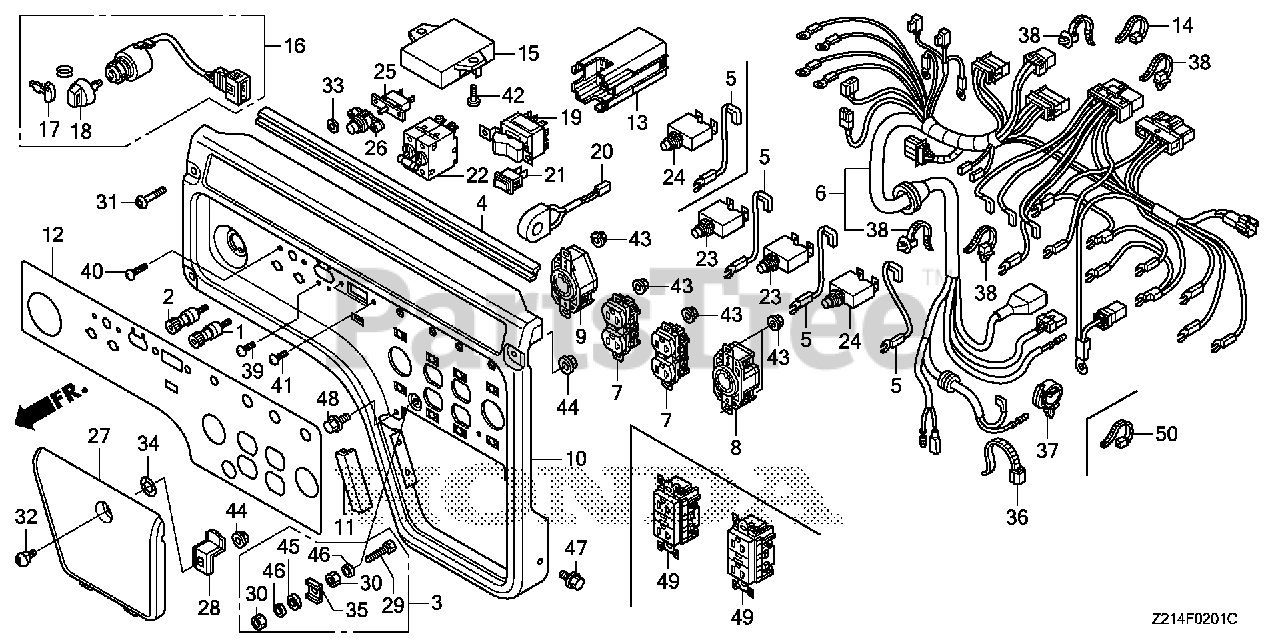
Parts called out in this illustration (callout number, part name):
1	TERMINAL, D.C. OUT (+)
2	TERMINAL, D.C. OUTPUT (-)
3	TERMINAL SET, GROUND
4	RUBBER, CONTROL PANEL
5	SUB-WIRE ASSY. (A)
6	WIRE HARNESS ASSY., CONTROL
8	RECEPTACLE (20A-125/250V)
9	RECEPTACLE (30A-125V)
10	PANEL, CONTROL (EM-A1) *R280* (POWER RED)
11	RUBBER, CONTROL PANEL (LOWER)
12	MARK, PANEL (EM-A1)
13	CONNECTOR (12P)
14	TIE, CABLE (C)
15	CONTROL UNIT ASSY., ENGINE
16	SWITCH ASSY., COMBINATION
18	KEY ASSY., COMBINATION SWITCH (BLACK)
19	SWITCH ASSY., VOLT CHANGE
20	SENSOR ASSY. (CT)
21	SWITCH, AUTO-THROTTLE (OTAX)
22	BREAKER, CIRCUIT (17A)
23	PROTECTOR, CIRCUIT (20A)
24	PROTECTOR, CIRCUIT (20A)
25	PROTECTOR, CIRCUIT (D.C.)
26	LENS ASSY., PROTECTOR
27	COVER (LOWER)
28	LOCK PLATE, COVER (LOWER)
29	BOLT, HEX. (6X28)
30	NUT, HEX. (6MM)
31	BOLT, SOCKET (8X22)
32	BOLT, MAINTENANCE LID LOCK
33	WASHER (4MM)
34	WASHER, WAVE (12MM)
35	RETAINER (6MM)
36	BAND, WIRE (95MM)
37	CLIP, WIRE HARNESS
38	CLIP, HARNESS BAND (145MM) (BLACK)
39	SCREW, PAN (3X5) (NOT AVAILABLE)
40	SCREW, PAN (3X16)
41	SCREW, PAN (4X6)
42	SCREW-WASHER (5X14)
43	NUT, FLANGE (4MM)
44	NUT, FLANGE (6MM)
45	WASHER, PLAIN (6MM)
46	WASHER, SPRING (6MM)
47	BOLT, FLANGE (6X10)
48	BOLT, FLANGE (6X14)
49	RECEPTACLE (20A-125V) (GFCI)
50	TIE, CABLE (C)
